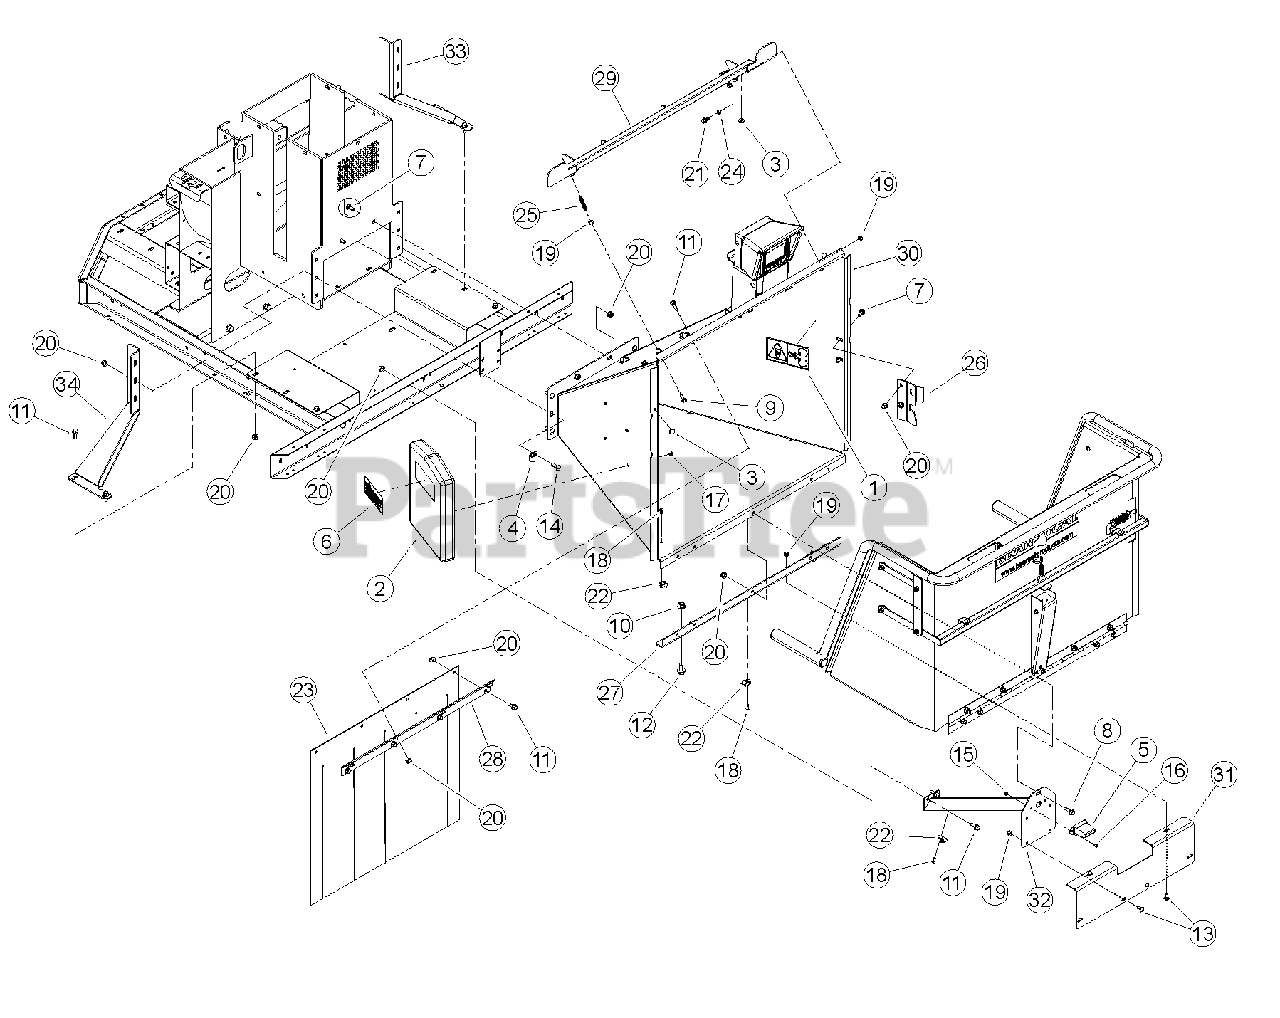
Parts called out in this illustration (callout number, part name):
1	DECAL, BLADE DANGER ISO
2	CONTAINER, INSTR. MANUAL
3	BUMPER, RUBBER
4	CLAMP, 9/16 COATED
5	LIGHT, LICENSE PLATE
6	DECAL, MULTILINGUAL MANUAL
7	BOLT, 3/8-16 X 1 GR5 CRG
8	BOLT, 3/8 X 1-1/4 FLANGE NC
9	BOLT, 5/16 X 3/4 FLANGE NC
10	NUT, 1/2-13 NYLOCK FLANGE
11	BOLT, 3/8 X 1 FLANGE NC
12	BOLT, 1/2-13 1.00 GR5 FLANGE NC
13	BOLT, 5/16 X 3/4 GR5 CRG NC ZP (CE COMPLIANT MODELS)
14	BOLT, 3/8-16 X 1-1/4 GR5 CRG
15	NUT, 10/24 NYLOCK TYPE NM ZP
16	SCREW, MCH 10-24 X 1/2" PAN HD PH ZP
17	RIVET, AL BLIND 1/4 X 1/2 DOME HEAD
18	RIVET, AL BLIND 1/4 X 3/4 DOME HEAD
19	NUT, 5/16-18 NYLOCK FLANGE
20	NUT, 3/8-16 NYLOCK FLANGE
21	BOLT, 5/16-18 X 3/4 ZP FLANGE SHOULDER
22	CLAMP, CABLE MOUNT
23	FLAP, CHUTE
24	BEARING, .375 X .50 X .25 LONG
25	SPRING, COMPRESSION .437 DIA X 2.0 LONG
26	PLATE, TRAY LATCH
27	ANGLE, 6" INFEED SUPPORT
28	SUPPORT, 6" CHIPPER FLAP
29	WELDMENT, 6" TOP SAFETY BAR
30	WELDMENT, 6" CHIPPER CHUTE
31	BRACKET, EUROPEAN LICENSE (CE COMPLIANT MODELS)
32	WELDMENT, CHUTE SUPPORT
33	PLATE, CHIPPER SUPPORT RH
34	PLATE, CHIPPER SUPPORT LH
